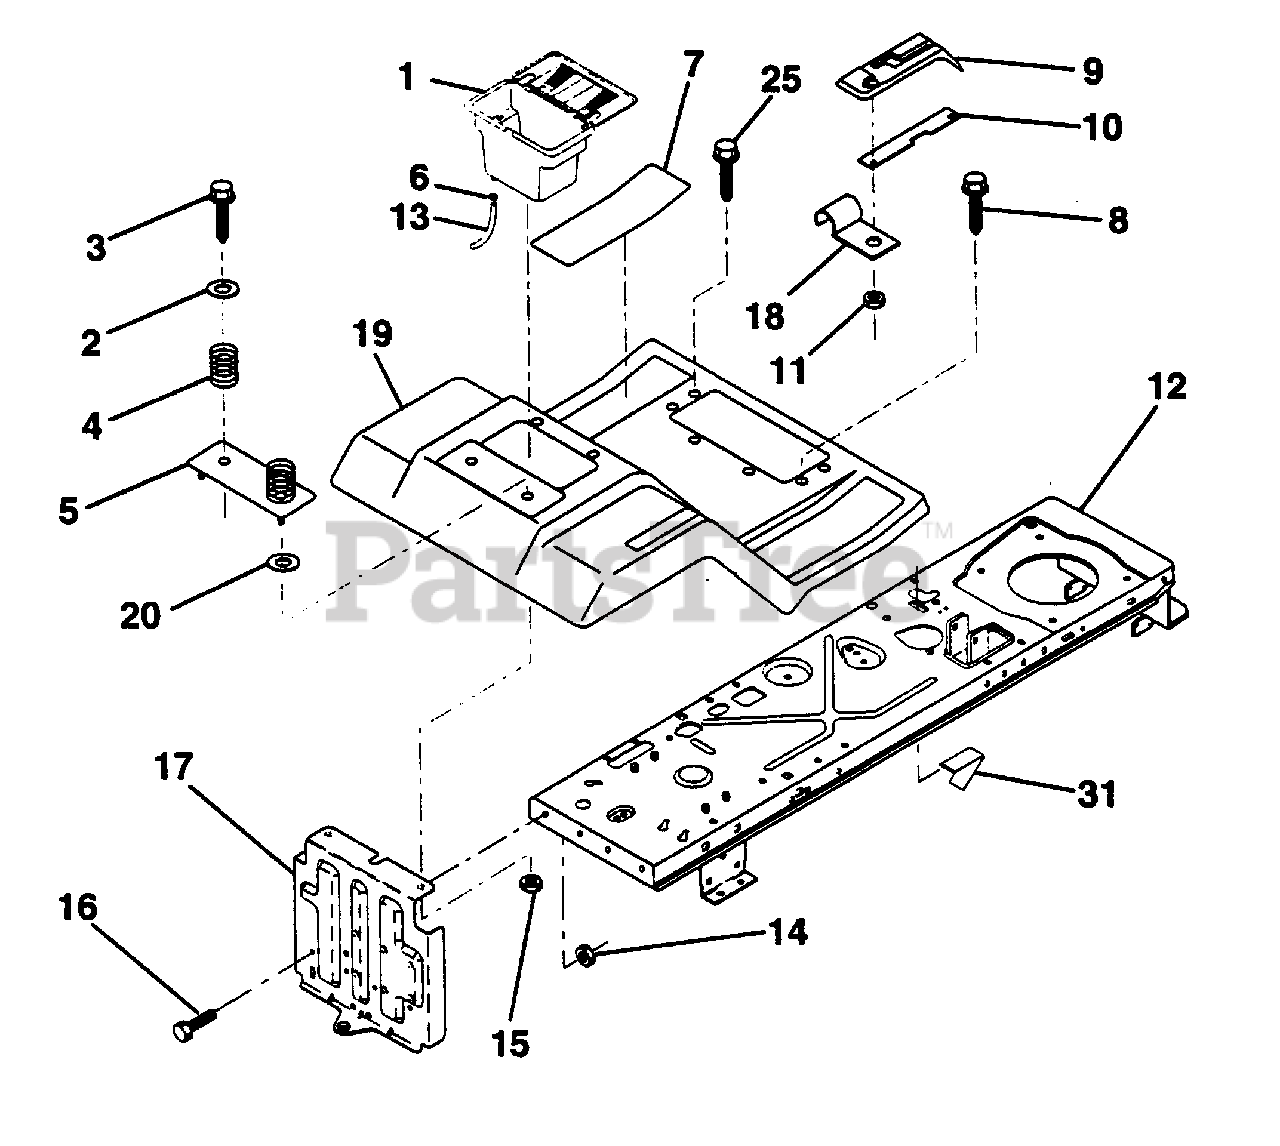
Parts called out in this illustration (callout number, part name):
1	Case, Battery (AYP part number)
2	Washer 13/32 x 1-1/4 x 12 Ga. (AYP part number)
3	Screw, Hex Wsh. Thrdrol. 3/8-16 x 3/4 (AYP part number)
4	Spring, Compression, Seat (AYP part number)
5	Plate, Asm. Battery (AYP part number)
6	Clamp, Hose (AYP part number)
7	Pad, Footrest (AYP part number)
8	Screw, Hex Wsh Thdrol. 5/16-18 x 3/4
9	Console, Shift Control (AYP part number)
10	Bar, Shift Lock (AYP part number)
11	Nut, Self-Thrd., Wsh. Head 3/16 (AYP part number)
12	Assembly, Frame (AYP part number)
13	Tube, Battery Drain (AYP part number)
14	Locknut, Hex W/Ins 5/16-18 (AYP part number)
15	Nut, Keps Hex 1/4-20 UNC (AYP part number)
16	Bolt, Hex Hd. 5/16-18 UNC x 3/4 (AYP part number)
17	Drawbar (AYP part number)
18	Clip, Insulated (AYP part number)
19	Fender/Footrest (AYP part number)
20	Washer 9/32 x 7/8 x 13 Ga. (AYP part number)
25	Screw Hex Wsh Thdroll 5/16-18 x 1 (AYP part number)
31	Switch Actuator (AYP part number)
